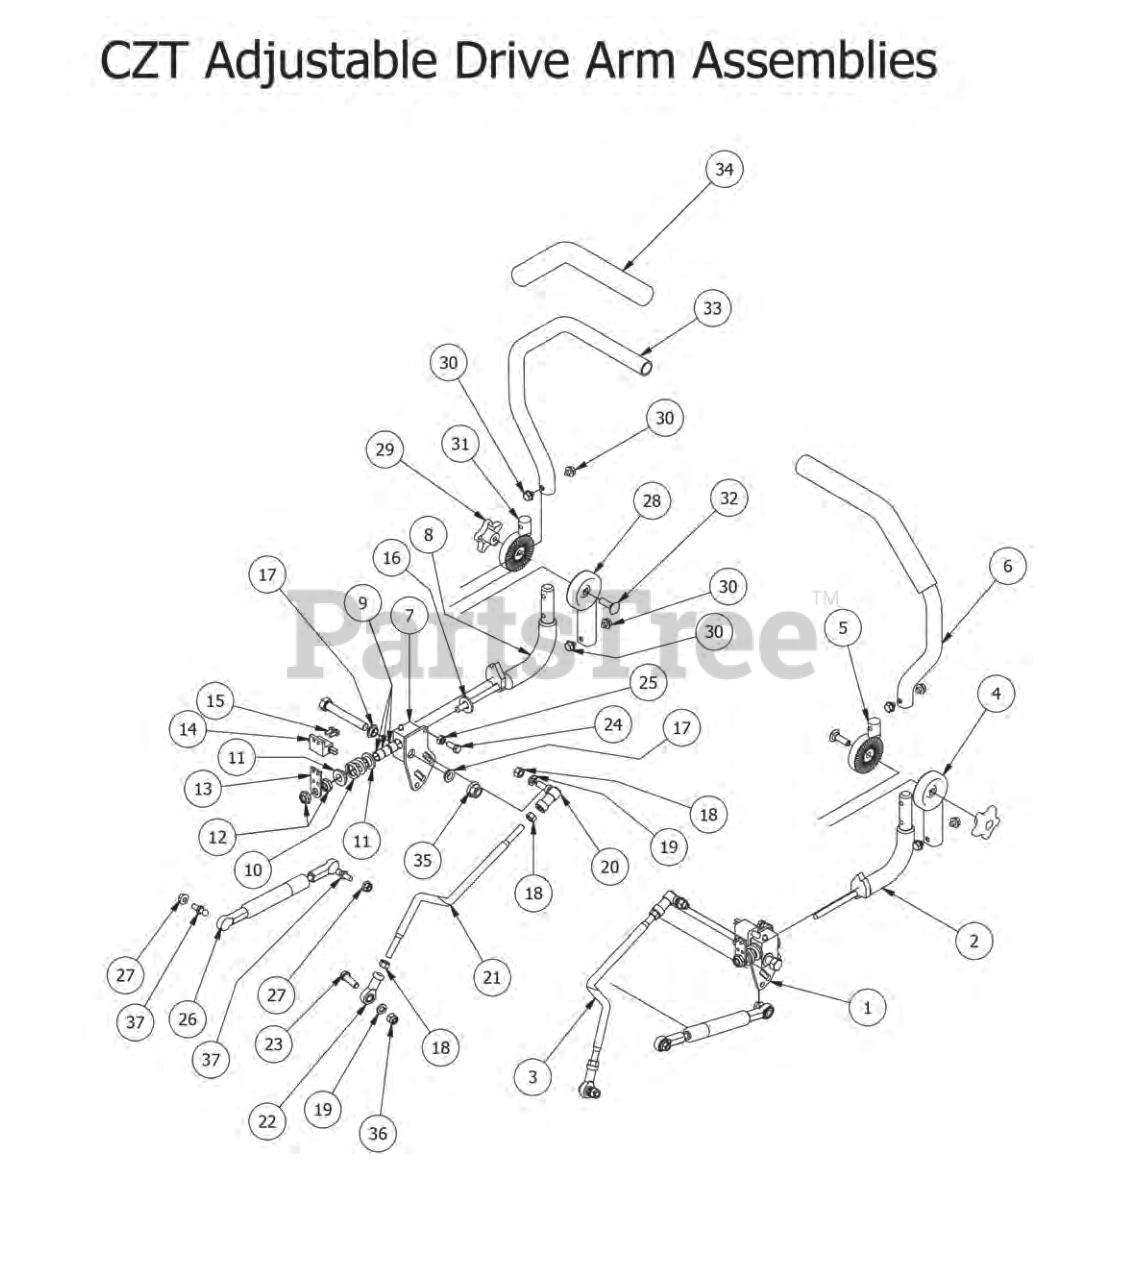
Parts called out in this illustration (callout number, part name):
1	2013 Drive Lever Housing (Right)
2	Steering Arm Elbow - Right
3	Push Rod for ZT/CZT - Right
4	Lower Adjuster - Steering Arm- Right
5	Upper Adjust Steering Arm- Right
6	Upper Tube-Adjustable Steering
7	2013 Drive Lever Housing (Left)
8	Steering Arm Elbow - Right
9	507 ID Nylon Bushing
10	Drive Lever Spring
11	515 ID Nylon Shoulder Washer
12	1/2" Nylcock Nut (1/2 Jam)
13	MZ Switch Bracket
14	Safety Switch
15	12-24x 1/2 HWH Bolt
16	505 Nylon Spacer
17	1/2" Oil Impregnated Bushing
18	3/8" Fine Threaded Jam Nut
19	3/8" Lock Washer
20	3/8-24 Quick Release Ball Joint
21	Push Rod for ZT/CZT - Left
22	Spherical Rod End - Outlaw
23	3/8" x 1 1/4" Hex Bolt
24	5/16" x 3/4" Hex Bolt
26	Steering Damper For Outlaw
27	5/16" Flange Nut
28	Lower Adjuster-Steering Arm- Left
29	Black Knob for Adjustable Steering Arm
30	5/16-18 1/2 HWH Bolt-Steering
31	Upper adjuster-Steering Arm- Left
32	3/8" x 1 1/4" Carriage Bolt
33	Upper Tube-Adjustable Steering
34	Black Steering Grip
35	1/2-13 Hex Flange (GR.G) ZC
36	3/8 Nylock Nut
37	10mm Damper Ball Stud-Steering
